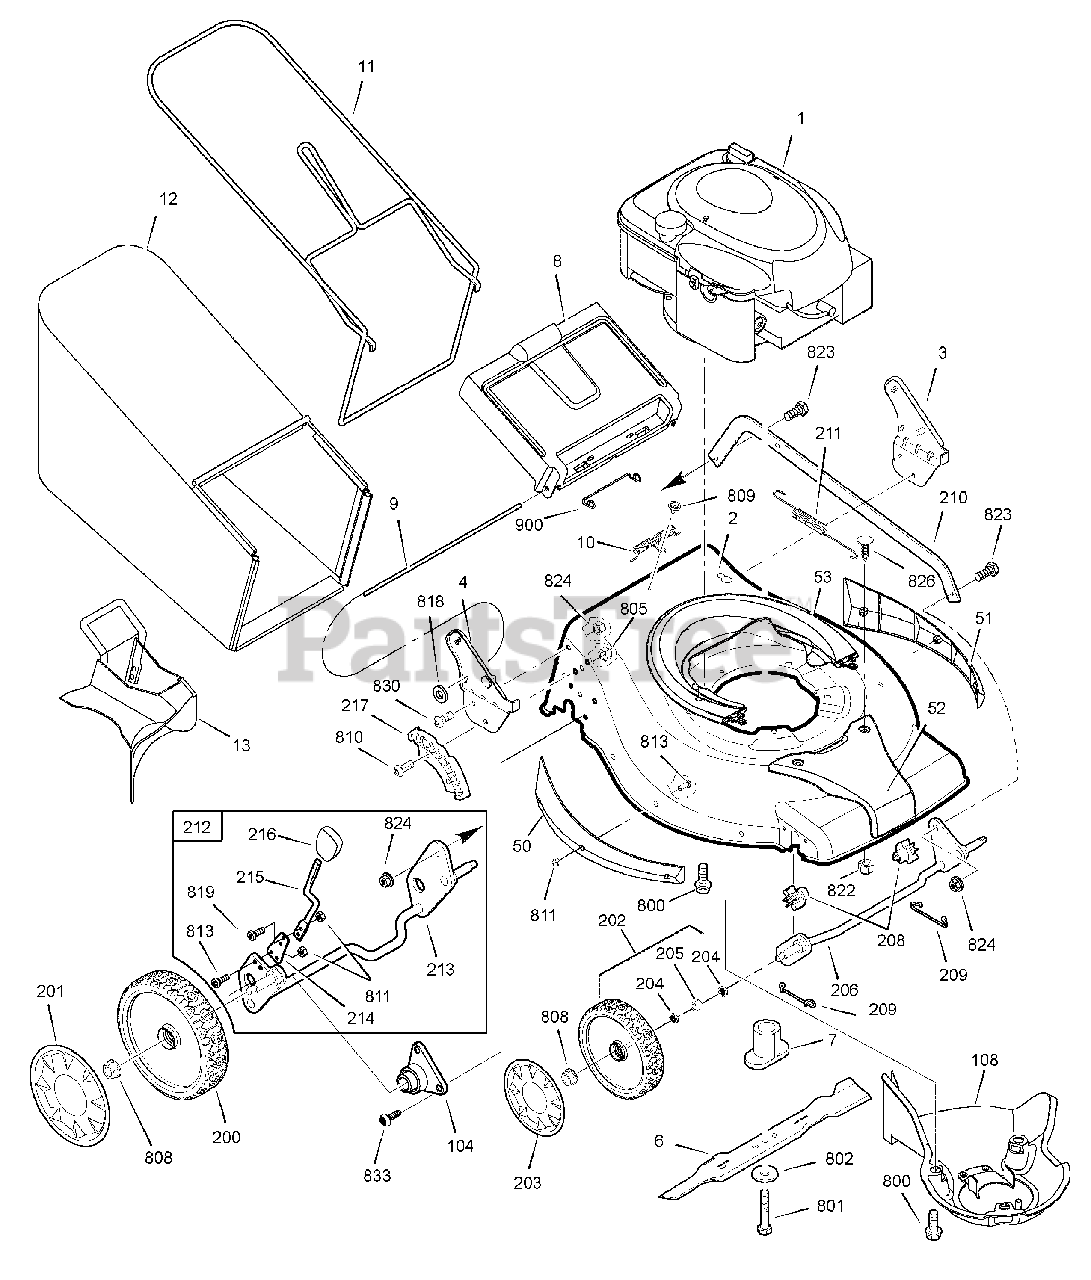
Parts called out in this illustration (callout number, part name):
1	* ENGINE, B&S 550 Series EU
2	MOWER HOUSING (Not Available)
3	BRACKET ASSEMBLY, Left Handle
4	BRACKET ASSEMBLY, Right Handle
6	BLADE, 19"
7	BLADE ADAPTER ASSEMBLY
8	DOOR, Rear
9	ROD, Rear Door
10	SPRING, Torsion Rear Door
11	FRAME ASSEMBLY
12	BAG ASSEMBLY
13	MULCH PLUG
50	SIDE GUARD, Right
51	SIDE GUARD, Left
52	HOUSING COVER, Front
53	HOUSING COVER, Rear
104	SLEEVE ASSEMBLY, Rear Axle
108	BELT COVER ASSEMBLY
200	WHEEL, Rear
201	HUBCAP, Rear
202	WHEEL, Front, 200MM 5 Spoke Tread II SI
203	HUBCAP, Front
204	WHEEL BEARING (Not Available)
205	SPACER (Not Available)
206	CROSSBAR ASSEMBLY, Front
208	BUSHING, Front Crossbar
209	SPRING, Clip Crossbar
210	LINK, Single Lever
211	SPRING, Extension
212	CROSSBAR ASSEMBLY, Rear (Not Available)
213	REAR CROSSBAR
214	SPRING, Adjuster
215	LEVER, Height Adjustment
216	KNOB, Adjuster
217	BRACKET, Height Adjuster
800	SCREW, Hex Head, 3/8-16 x 1
801	BOLT, Blade, 3/8-24 x 2
802	WASHER, Belleville
805	NUT, Nylock, M8 x 1-1/4
808	NUT, Flange, 3/8-16
809	SCREW, Self Tap, #10-16 x 1/2
810	BOLT, Hex Key Head
811	NUT, Nylock
813	SCREW, Torx Head, M5 x .8 x 14mm
818	NUT, Speed
819	SCREW, Torx Head, M5 x .8 x 12.5mm
822	NUT, Hex, 1/4-20
823	BOLT, Shoulder, 5/16-18 x 1
824	Nut, Flange, 5/16-18
826	SCREW, 1/4-20 x 7/8
830	SCREW , 5/16-18 x 3/4
833	SCREW, Torx, 1/4-20 x 5/8
900	SPRING CLIP, Rear Door
